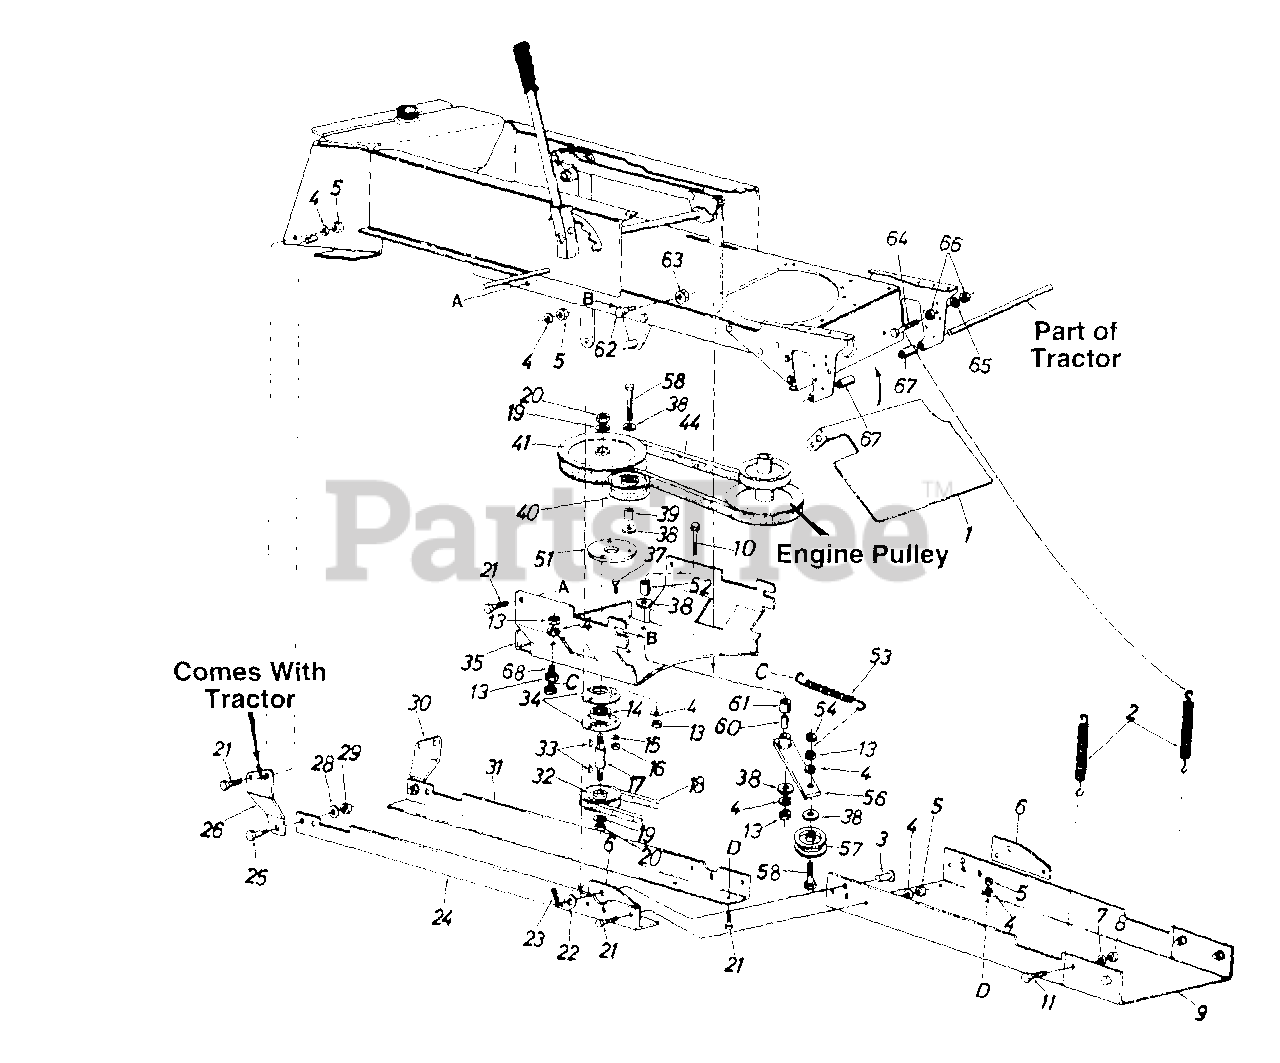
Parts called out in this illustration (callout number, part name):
3	Clevis Pin
4	L-Wash. 3/8" I.D.
5	Hex L-Nut 3/8-24 Thd.
6	Attaching Plate
7	L-Wash. 1/2" I.D.
8	Hex L-Nut 1/2-20 Thd.
11	Hex Bolt 1/2-20 x 1.25" Lg.
13	Hex Jam Nut 3/8-16 Thd.
14	Ball Bearing
15	L-Wash. 5/16" I.D.
16	Hex Nut 5/16-18 Thd.
18	"V"-Belt
19	L-Wash. 5/8" I.D.
20	Hex Jam Nut 5/8-11 Thd.
21	Hex Bolt 3/8-24 x 1.00" Lg.
23	Internal Cotter Pin
29	Hex Nut 7/16-14 Thd.
33	#6 Hi-Pro Key 3/16 x 5/8" Dia.
34	Bearing Housing
35	Supporting Bracket
37	Hex Sems Bolt 5/16-18 x 1"
38	Fl-Wash. .38" I.D. x 1" O.D.
39	Spacer .38" I.D. x .62" O.D.
40	Fl-Idler Pulley
41	Upper Drive Pulley
44	"V"-Belt
53	Extension Spring 4.75" Lg.
54	Hex L-Nut 3/8-16 Thd.
56	Idle Arm Ass'y.
57	Idler Pulley
58	Hex Bolt 3/8-16 x 2.25" Lg.
60	Spacer .377" I.D. x .83" Lg.
61	Spacer .38" I.D. x .565" Lg.
62	Shoulder Bolt .498" Dia.
63	Hex L-Nut 3/8-16 Thd.
64	Hex Bolt 1/4-28 x 1.50" Lg.
65	L-Wash. 1/4" I.D.
66	Hex Nut 1/4-28 Thd.
67	Spacer .63" I.D. x 1.75" Lg.
68	Hex Bolt 3/8-16 x 2" Lg.
